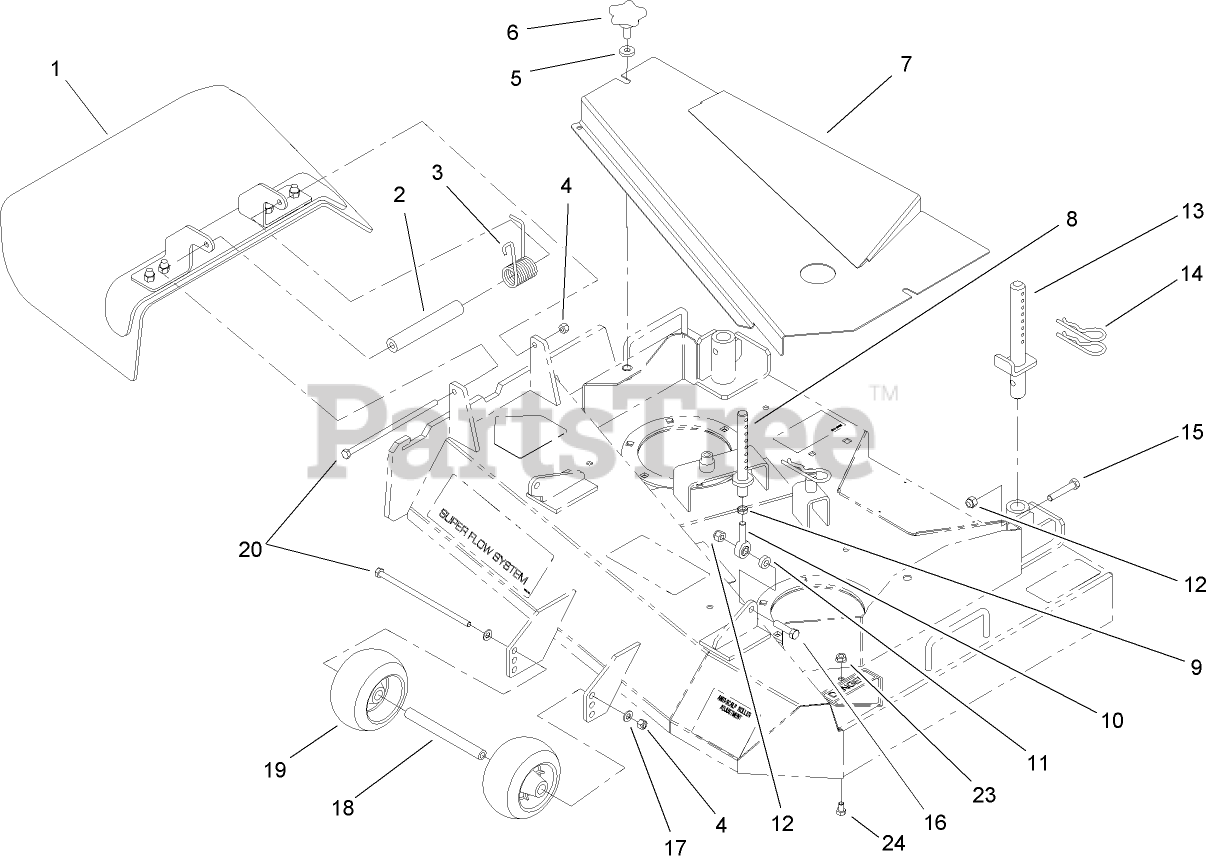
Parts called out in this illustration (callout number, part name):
1	DEFLECTOR ASM
2	SPACER
3	SPRING-TORSION
4	NUT-LOCK, NI
5	WASHER-RUBBER
7	Cover ASM
8	FRONT PIN ASM
9	NUT-HJ
10	BALLJOINT
11	SPACER
12	NUT-LOCK, NI
13	REAR PIN ASM
14	PIN-HAIR
15	SCREW-HH
16	SCREW-HH
17	WASHER-PLAIN
18	SPACER-WHEEL
19	ROLLER-SCALP, ANTI
20	SCREW-HH
23	NUT-HF
24	SCREW-HH
